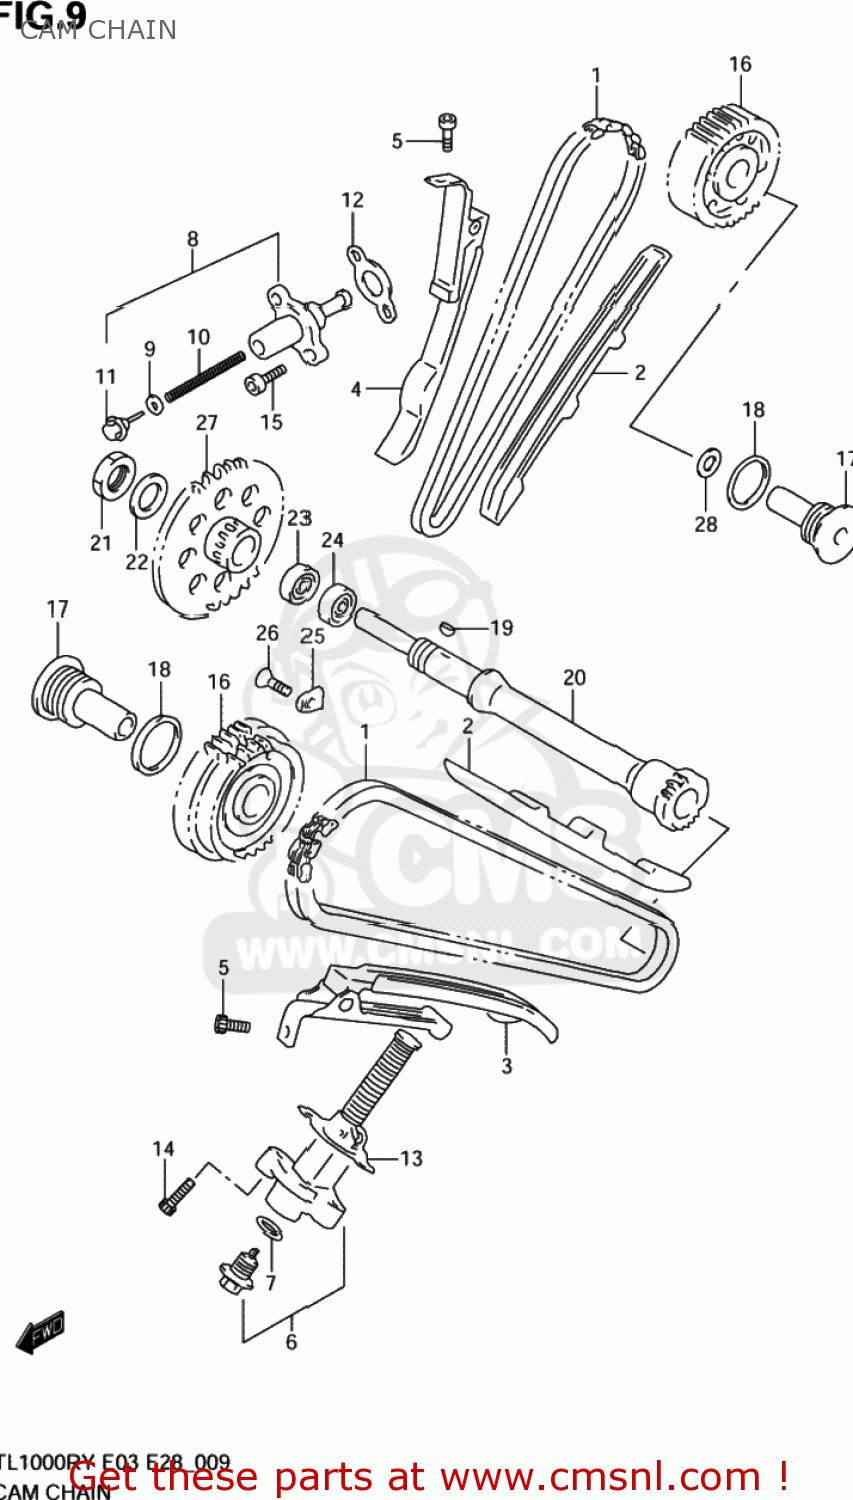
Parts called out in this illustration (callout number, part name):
1	CHAIN,CAMSHAFT DRIVE
2	GUIDE,CAM CHAIN
3	TENSIONER,CAM CHAIN FR
4	TENSIONER,CAM CHAIN RR
5	BOLT
6	ADJUSTER ASSY,TENSIONER FR
7	GASKET(12X21X2) (NAS)
8	ADJUSTER ASSY,TENSIONER
9	O RING
10	SPRING
11	PLUG,ADJUSTER
12	GASKET,TENSIONER ADJUSTER (NAS)
13	GASKET,TENSIONER ADJUSTER (NAS)
14	BOLT,CL.COVER
15	BOLT,CRKCASE,R
16	GEAR,CAM CHAIN IDLER NO.2
17	SHAFT,IDLER NO.2
18	GASKET(26.5X30.5X1) (NAS)
19	KEY
20	SHAFT,IDLER
21	NUT
22	SHIM(16X26X1.5)
23	BEARING
24	BEARING(25X47X10)
25	RETAINER,COUNTER BEARING,R
26	SCREW
27	SPROCKET,IDLER NO.1
28	SHIM(15X24X1)
